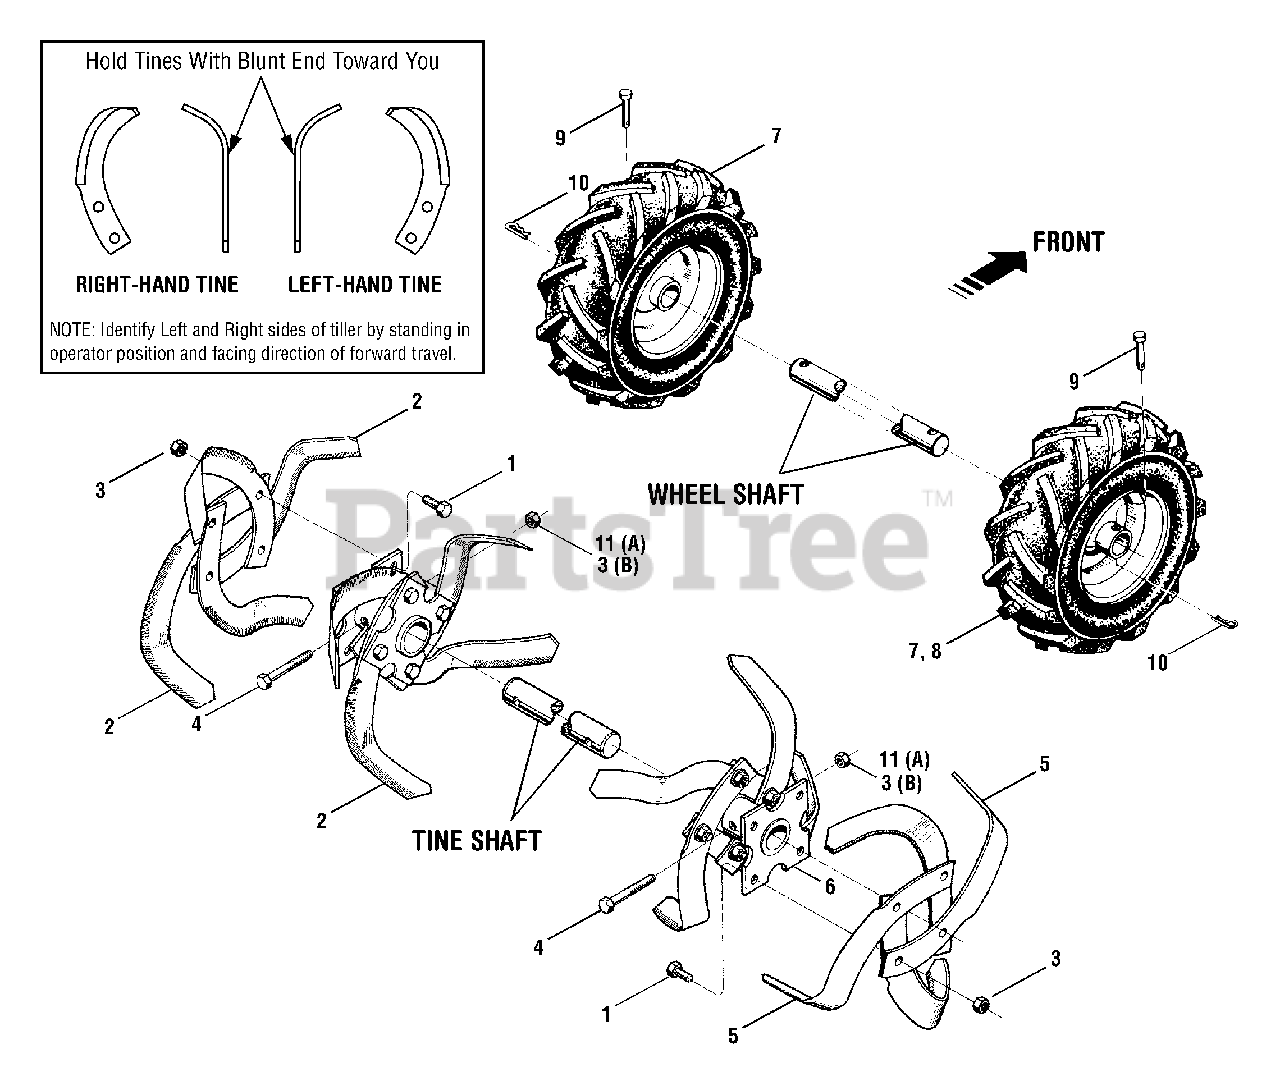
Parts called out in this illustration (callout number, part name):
1	Hex Hd. Screw, 3/8-16 x 1, Grade 5
2	Single Bolo Tine - Left Hand
3	Hex Lock Nut, 3/8-16
4	Hex Hd. Screw, 3/8-16 x 1-3/4
5	Single Bolo Tine - Right Hand
6	Tine Holder
7	Wheel & Tire Ass'y - Left/Right Side
8	Wheel & Tire Ass'y - Right Side Only
9	Clevis Pin,.312" x 1-3/4"
10	Hair Pin Cotter
11	Flange Lock Nut, 3/8-16
